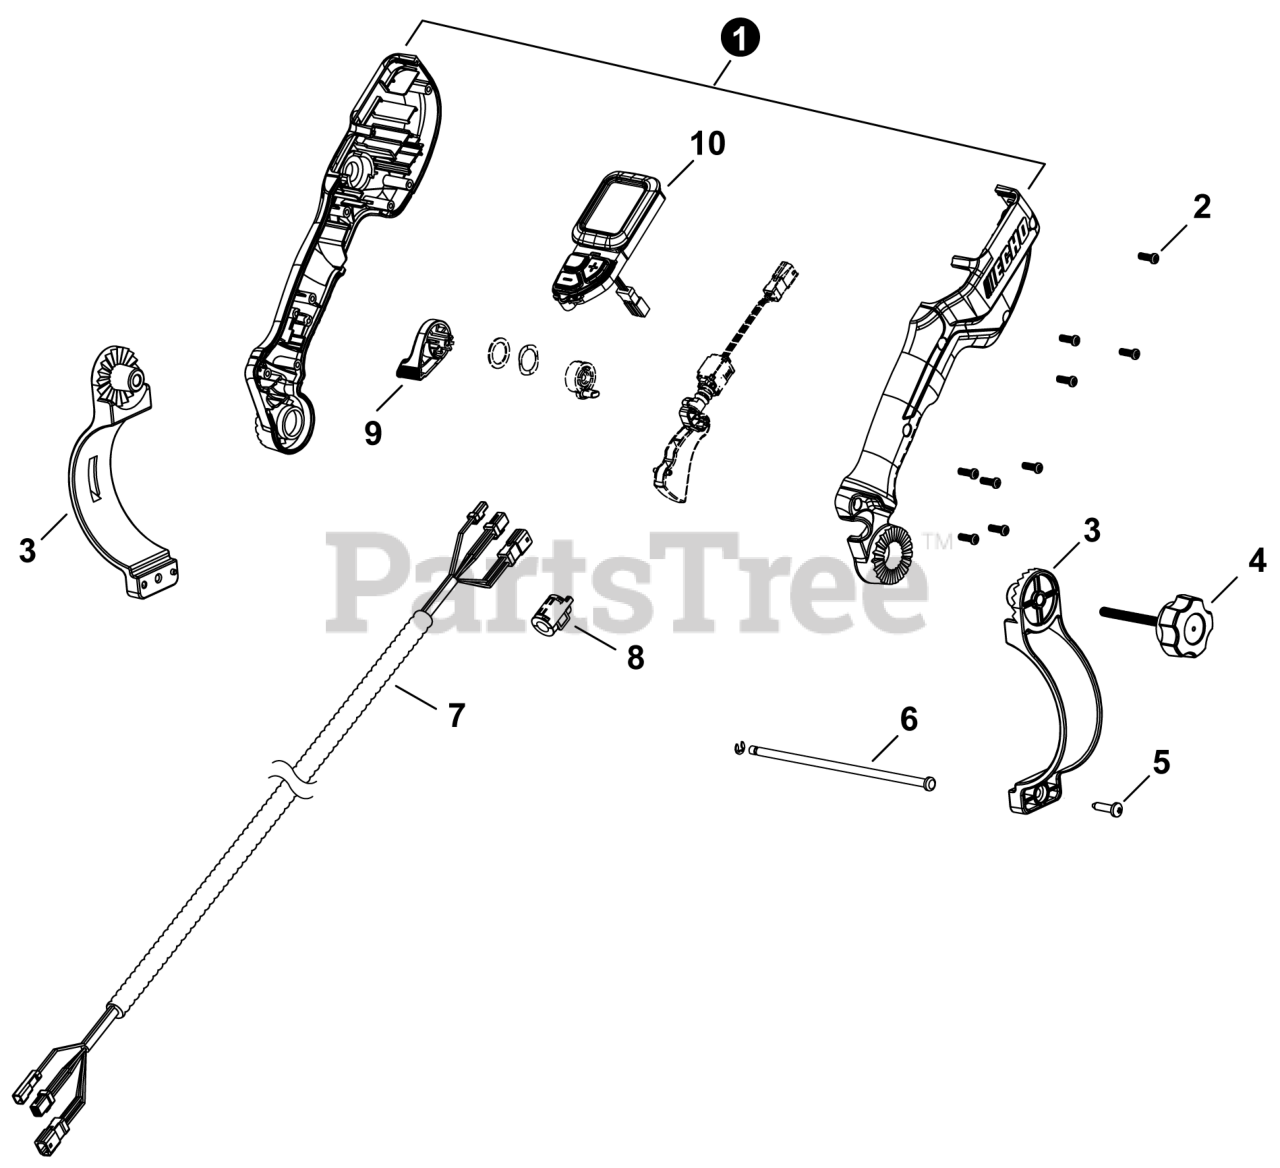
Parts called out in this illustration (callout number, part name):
1	HANDLE, CONTROL - SET
3	CLAMP, BLOWER TUBE
4	SCREW, KNOB
6	ROD, CLAMP
7	HARNESS ASSY., WIRING
8	SHIELD, EMC
9	KNOB, CRUISE CONTROL
9	LEVER, THROTTLE
10	SWITCH, SPEED CONTROL
10	CONTROL ASSY.
11	CONTROL ASSY.
12	KNOB, CRUISE CONTROL
